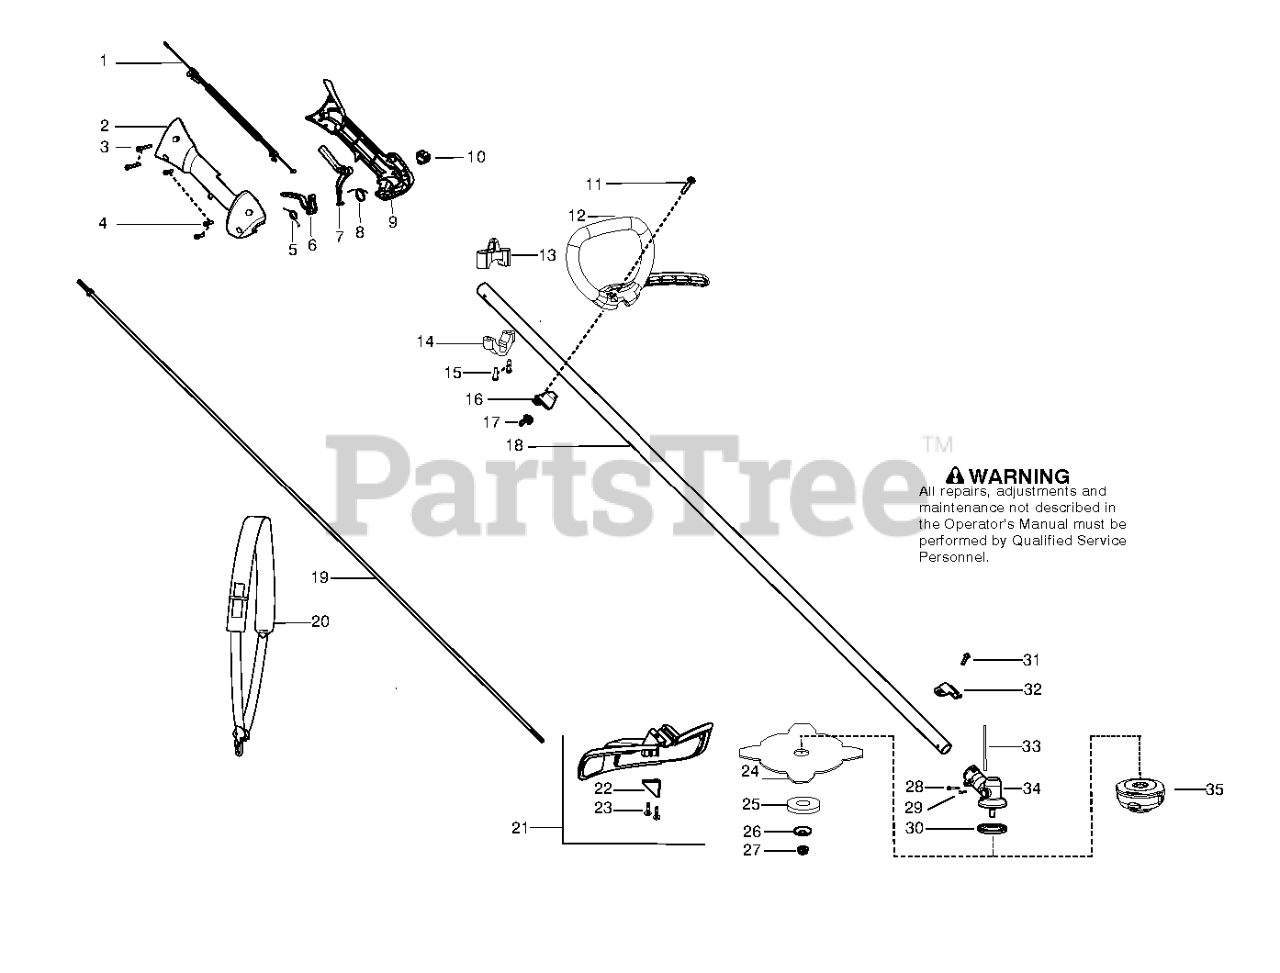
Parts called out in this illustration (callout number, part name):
1	IGNITION COIL ASSY
2	IGNITION CABLE
3	TUBE
4	SPARK PLUG CAP
5	SPRING
6	SPARK PLUG NGK BPMR-8Y
7	BOLT M4 X 25
9	SHORT CIRCUIT CABLE
11	CLUTCH DRUM
14	CLUTCH ASSY Φ56
15	CLUTCH SPRING
16	NUT
